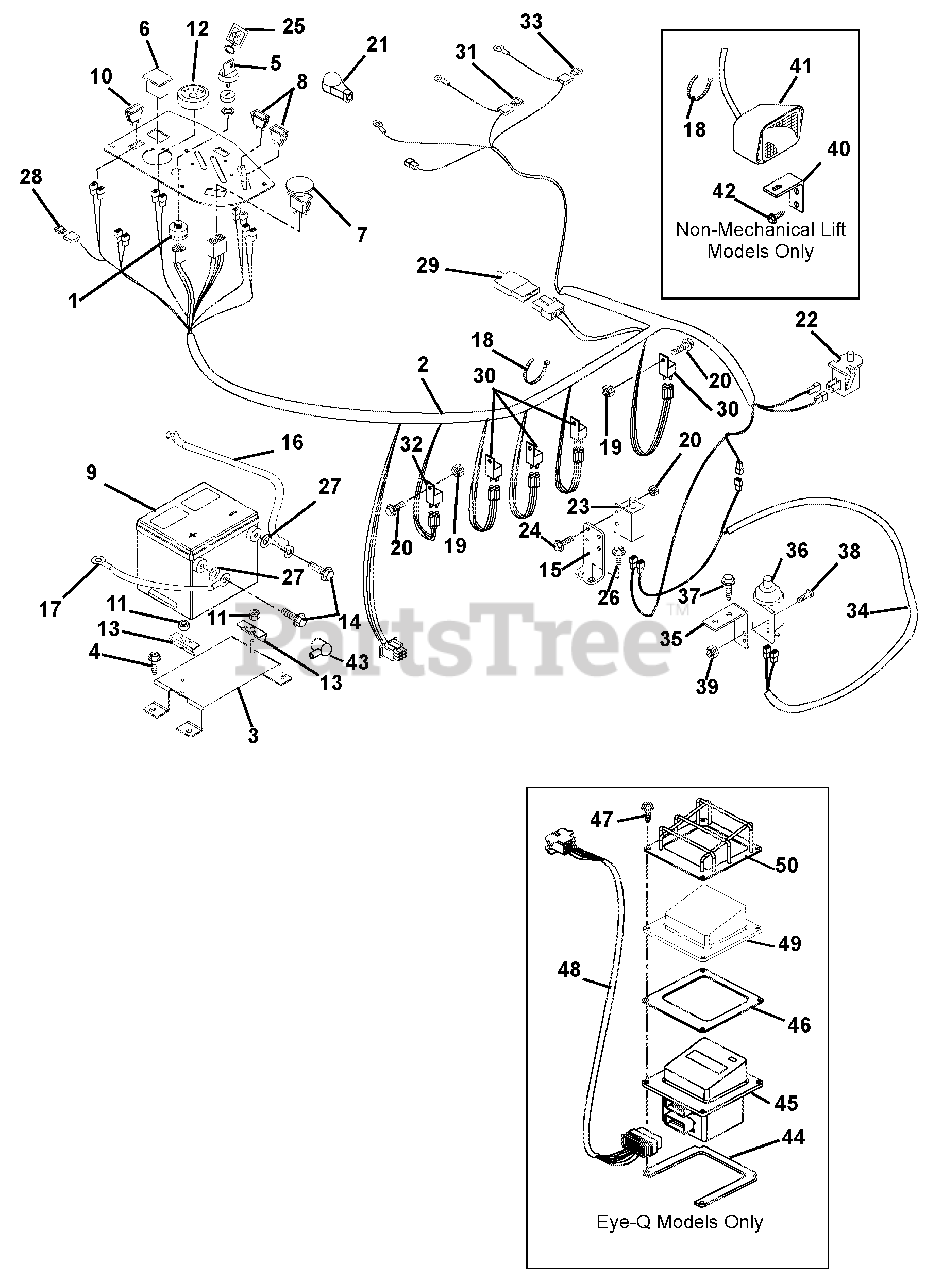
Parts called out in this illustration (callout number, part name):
1	Switch, Ignition (Diesel)
2	Harness, Wiring (Diesel)
3	Weldment, Battery Support
4	Screw-Tapping .38-16 x .75 Hex Washer Head
5	Key-with Cap
7	Switch-Clutch With Retainer Ring
8	Light-Indicator Kit
9	Battery with Tube
10	Switch, Light
11	Nut-Locking-Top-Flange .31-18
12	Gauge, Temperature
13	Bracket, Battery Hold-Down
14	Bolt-Hex .25-20 x .75 Grade 5
15	Mount, Safety Switch
16	Positive Cable
17	Cable, Negative Battery
18	Cable Tie
19	Screw-Machine 10-24 x .75 Hex Washer Head
20	Nut-Locking-Nylon 10-24 With Insert
21	Eyelet Terminal Boot
22	Switch, Snap Mounting (N.O.) (Included with Seat)
23	Switch-Single Pole
24	Screw-Machine 10-24 x .75 Hex Washer Head
25	Key Chain
26	Screw-Tapping .25-20 x .50 Hex Washer Head
27	Washer-Flat-Steel .406 x 1.00 x ..083
28	Fuse, 15 Amp
29	Diode, Connector Shell
30	Relay (Included with Harness)
31	Fuse, 30 Amp (Included with Harness)
33	Fuse, 50 AMP (Maxi Fuse) (Included with Harness)
34	Harness, Wire Adapter CE
35	Mount - Switch
36	Switch - Single Pole (N.O.) with Cover
37	Screw - Tapping .31-18 x .50 Hex Washer Head
38	Screw - Machine 10-24 x .75 Hex Washer Head
39	Nut-Locking-Nylon 10-24 with Insert
40	Bracket, Headlight Mounting
41	Headlight
42	Screw-Tapping .38-16 x .50 Hex Washer Head
43	Boot, Eyelet Terminal
44	Spacer, Enclosure Mounting (Bottom)
45	Assembly, Eye-Q
46	Gasket, Eye-Q
47	Screw, Machine 10-24 x 1.0 Slotted Pan Black
48	Harness Jumper (Eye-Q)
49	Guard, Element
50	Guard, Vinyl Eye-Q
